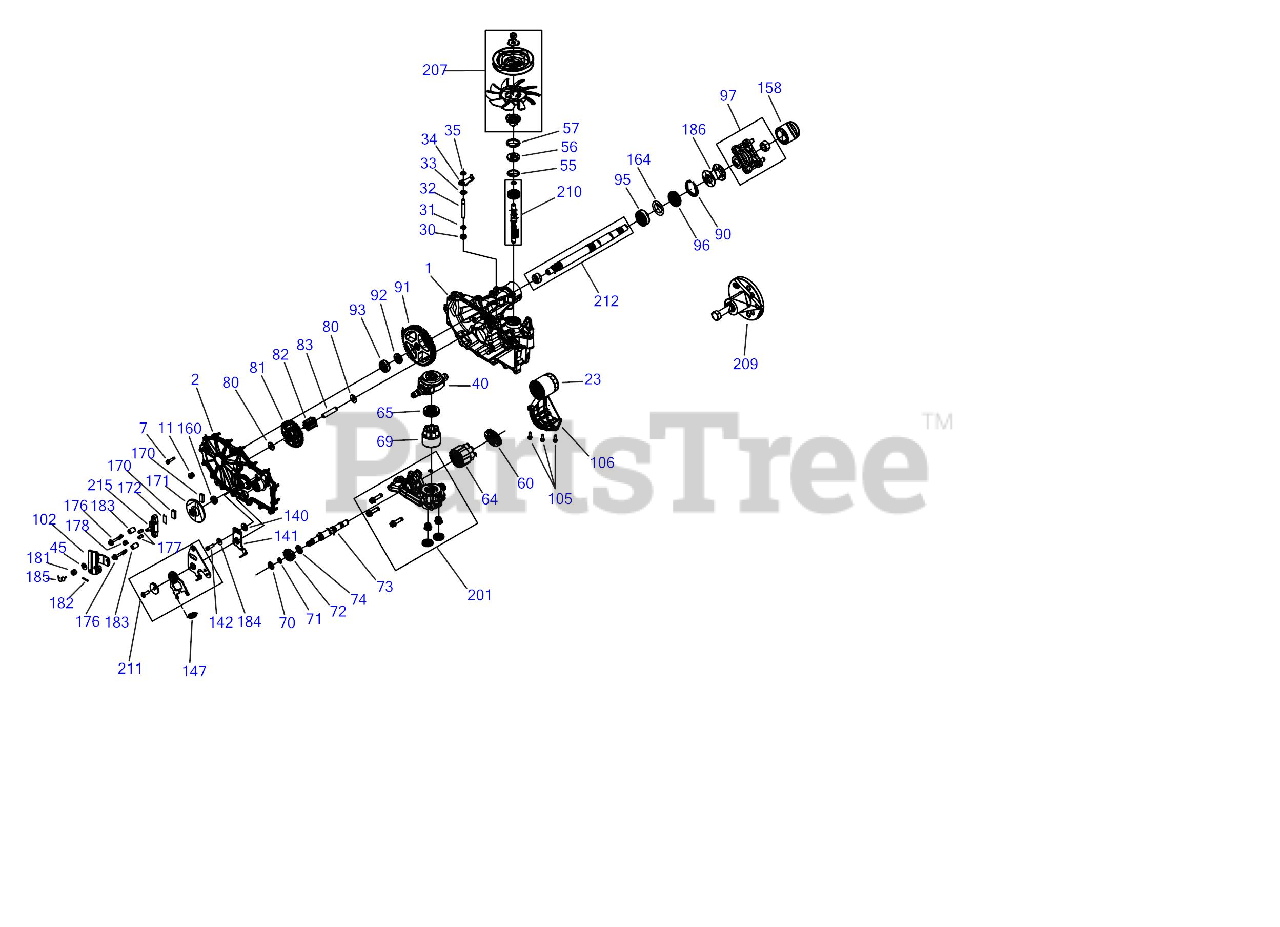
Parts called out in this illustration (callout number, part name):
1	Kit, Housing, Main, LH
2	Kit, Cover Side LH Control
7	Screw, Hex Washer
23	Filter, Spin-On 2.6 x 3.0
30	Seal, Lip, .375 x .75 x .25
31	Ring, Retaining .375 External
32	Rod, Bypass
33	Ring Retaining .750 Internal
34	Arm, Bypass
35	Ring, Ret .375 External
40	Trunnion, Swashplate
45	Washer, .34 x .88 x .06
55	Washer, 1.23 x 1.57 x .04
56	Seal, Lip 17 x 40 x 7
57	Ring Retaining Internal
60	Bearing, Thrust 35 x 62 x 18
64	Kit, 16cc Cylinder Block Assembly
65	Thrust Bearing, 30 x 52 x 13
69	Kit, Block, 7 Piston
70	Washer, .63 x 1.00 x .05
71	Ring, Reatining, Motor Shaft
72	Gear, 16T
73	Shaft, Motor
74	Washer, .71 x 1.16 x .04
81	Gear, 43T
82	Gear, 11T
83	Pin, Jackshaft
90	Ring, Retaining 2.25 Internal
91	Gear, 54T
92	Spacer, .750 x 1.00 x .257
93	Bearing, Ball 3/4 x 40mm x 12mm
95	Bearing, Ball 25.4 x 52 x 15
96	Seal, Lip, 1.0 x 2.06 x .38
97	Kit, Hub 4-Bolt
102	Arm, Brake
105	Screw, Hex Washer 1/4-20 x .75
106	Guard, Filter, LH
140	Spacer, .320 x 1.005 x .150
141	Arm, Neutral Right
142	Socket Cap Screw, 5/16-24 x 7/8
147	Spring, Extension
158	Cap, Axle
160	Seal, Lip .625 x 1.00 x .250
164	Spacer, 1.355 x 2.035 x .021
170	Puck, Brake
171	Rotor, Brake
172	Puck, Plate
176	Screw, .250-20 x 2.0 HFS Patch
177	Pin, Brake Actuating
178	Compression Spring
181	Nut, Castle 5/16-24
182	Pin, Cotter 3/32 x 3/4
184	Washer, .34 x .88 x .06
185	Spring, Brake Arm Bias
186	Tube, Axle 2.03
201	Kit, Center Section RH
207	Kit, Fan Pulley
207	Fan Only
207	Pulley Hub
209	Kit, Hub Puller
210	Kit, Input Shaft
211	Kit, RTN Bidirectional
212	Kit, Shaft Axle
215	Kit, Brake Yoke
